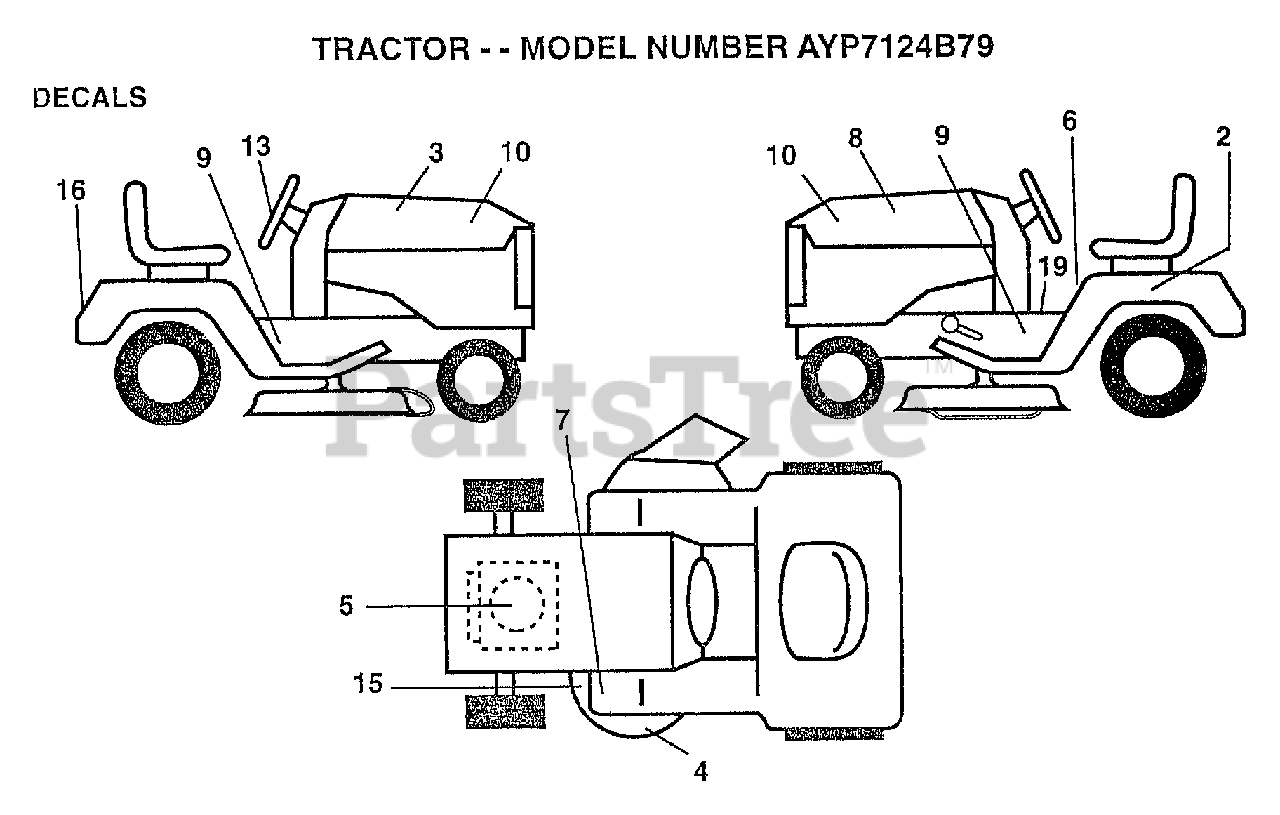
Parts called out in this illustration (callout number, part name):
2	DECAL.BATRY.3-3908
3	DECAL.HD.RH.WIZAR
4	DECAL DECK WIZ +
5	DECAL, HP ENGINE
6	"DECAL DANGER,FEND"
8	DECAL.HD.LH.WIZAR
9	DECAL CHASSIS
10	NAMEPLATE WIZARD
13	DECAL.INS.STRG.WL
15	DECAL
19	"DECAL DASH,OPER."
